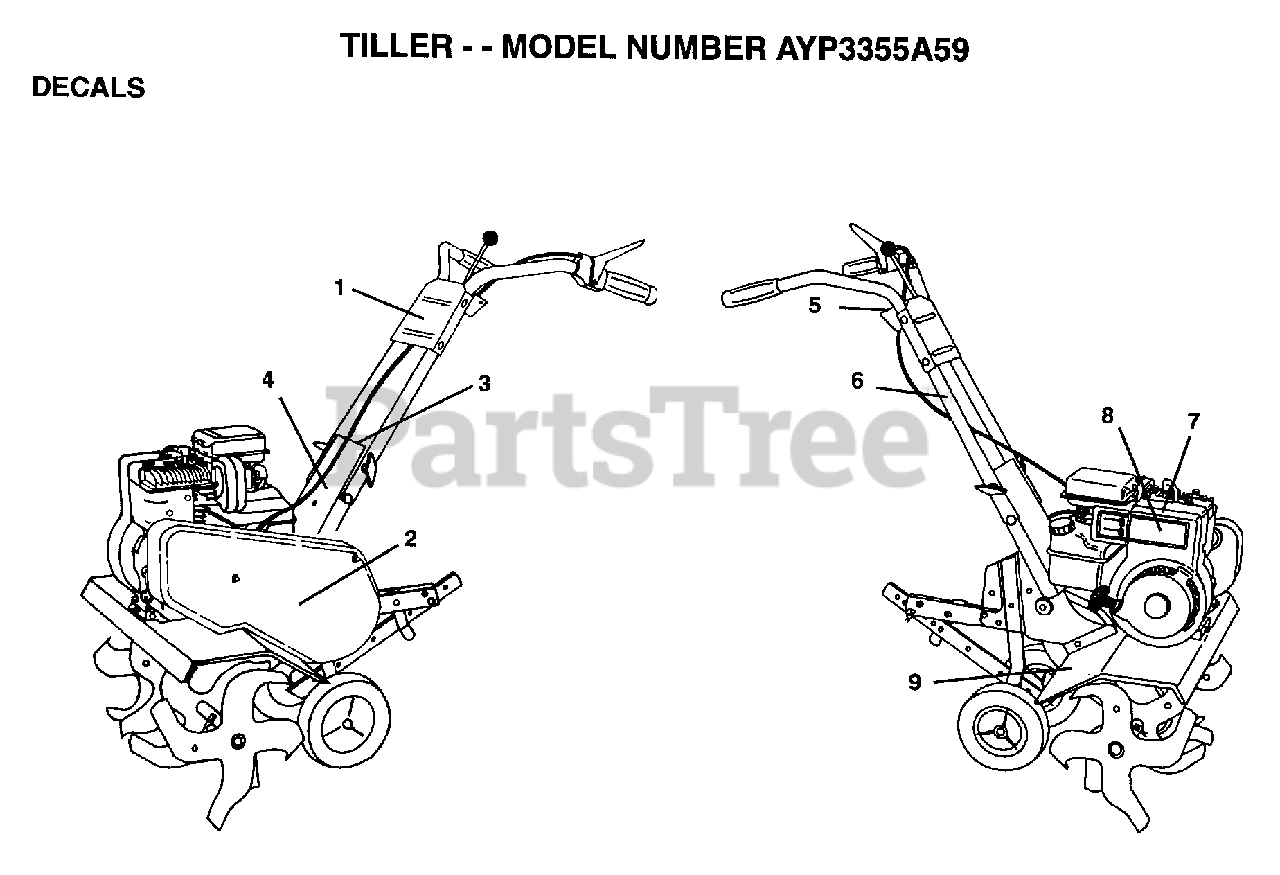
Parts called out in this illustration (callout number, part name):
1	DECAL.CNTRL.PNL.5
2	DECAL.BELT.GUARD
3	DECAL, LOGO
5	DECAL REVERSE
6	DECAL TI
8	DECAL, BRIGGS & STRATTON
9	DECAL TI
